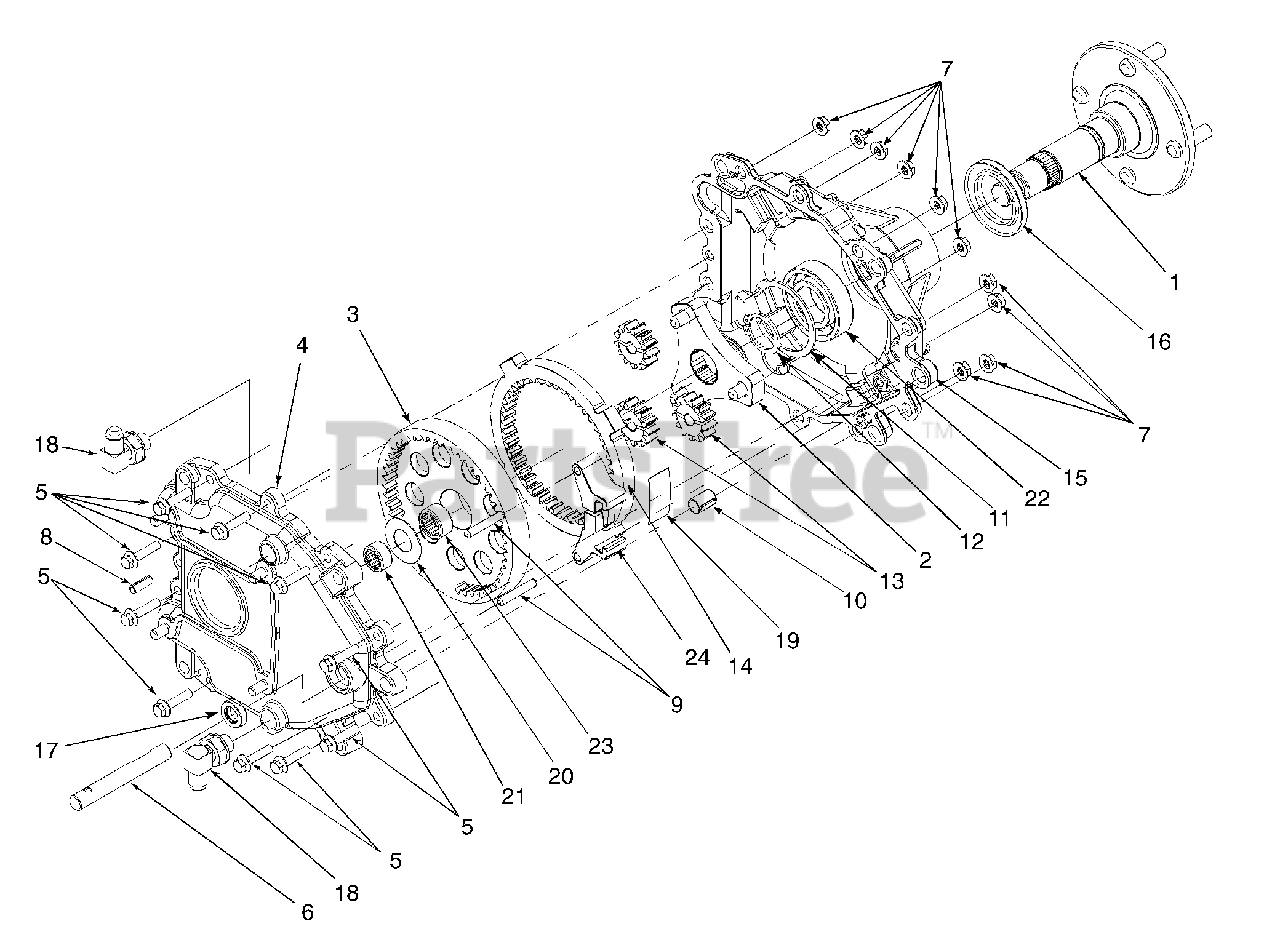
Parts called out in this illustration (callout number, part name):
1	Axle Assembly
2	Carrier Assembly, Output
3	Gear Assembly, 51T Internal & 20T,
4	Housing Ass'y, Inner
5	Screw, Hex Wash. Hd. 1/4-20 x 1-1/8
6	Shaft, Brake
7	Nut, Hex Flange Lock, 1/4-20
8	Pin, Roll, .25 x .75
9	Pin, Dowel, .250 x 1.50
10	Bushing, Dowel
11	Ring, Inverted Retaining
12	Ring, Snap, 1.189 Dia. Shft.
13	Gear, Spur, 13T
14	Gear, Ring, 46T
15	Housing, Axle Outer
16	Seal, Oil
18	Fitting, Elbow, 3/8 x 3/8
19	Spring, Brake Shoe
20	Washer, Shim, .76 x 1.5 x .030
21	Bearing, Needle
22	Bearing, Ball
23	Bearing, Needle
